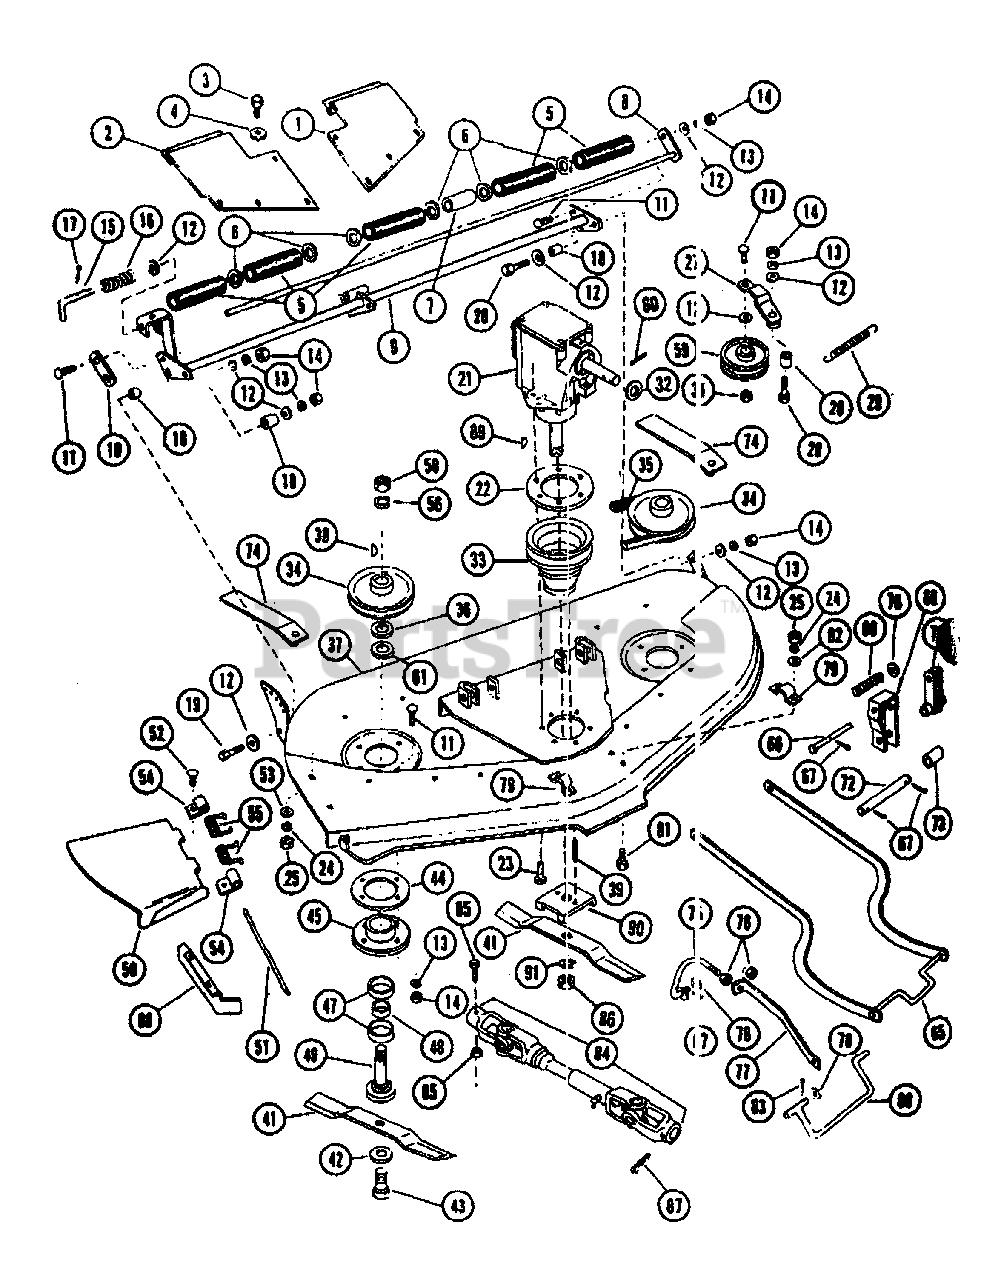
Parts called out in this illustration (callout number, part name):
1	SHIELD ASSEMBLY
2	R.H. BELT SHIELD
3	SCR-TAP .250-20X.50 HH F
4	WSHR-FL-STL.281X.62X.065 PL
6	WSHR-FL-STL.656X1.312X.095 PL
7	SPACER .692X.812X2.125
8	ROLLER SHAFT
9	ROLLER ADJUSTMENT
11	BLT-RDHDSQNK .38-16X1.0 PL
12	WSHR-FL-STL .438X1.0X.083 PL
13	WSHR-LK .375X.094 MED PL
14	NUT-HEX .375-16
16	SG-COMP .063X.63X1.75 WLD10
17	PIN-COTR .12X.75 PL
18	BSHG-SLV .377X.624X.235
19	BLT-HEX .38-16X1.25 PL GR 2
20	BLT-HEX .38-16X1.00 PL
21	MOWER GEAR CASE 42 IN
22	SHIM
23	BLT-LK .31-18X.75 GR 5
24	WSHR-LK .312X.097 PL HVY
25	NUT-HEX .312-18
26	BSHG-SLV .375X.625X.1.000
27	IDLER ARM
28	BLT-HEX .38-16X1.75 PL GR2
29	SG-TENS .125X.812X5.25 WLD 15
31	NUT-LK-JAM-CTR .375-16 PL
32	WSHR-FL-STL .754X1.000X.032
34	PLY-V 4.50 X .75 W/KEY SALEM
35	V-BELT, HA-WRAPPED
36	WSHR-FL-STL .781X1.250X.059 PL
37	DECK ASSEMBLY
38	KEY-WDRF .188X.75X.313 SAE 9
39	PIN-GRV .188X.75 TP A
40	SCR-MCH .31-18X1.00 SLFL PL
42	BELLEVILLE WASHER
43	BLT-HEX .44-20X1.00 GR5
45	FLANGED BEARING HOUSING
47	BRG-BALL .750X1.781X.61
48	SPACER .807X1.001X.445
49	SPINDLE SHAFT
50	CHUTE EXTENSION
51	CHUTE PIVOT ROD
52	BLT-RDHDSQNK .312-18X.62SHTPL
53	WSHR-FL-STL .38X.875X.083 PL
54	CHUTE HINGE
55	SG-TORS .080X.28X1.30
56	WSHR-LK-INT .750X.050 MED
58	NUT-JAM .75-16 PL
59	IDLER-FLAT 3.00 X .38 CLK.&CAP
60	PIN-ROLL .125X1.00
61	WSHR-FL-STL .755X1.375X.062 PL
65	MOWER HANGER
66	PIN-CLEV .498X4.50 YWZC
67	PIN-COTR .12X1.0 PL
68	SUPPORT CHANNEL
69	SG-COMP .62X.68X1.75
70	WSHR-FL-STL .531X1.062X.095 PL
72	PIN-CLEV .498X4.31 YWZC
73	SPACER .516X.749X.938
74	RAMP
75	ADJUSTING ROD
76	NUT .50-13 PL
78	WSHR-FL-STL.563X1.37X.109PL
80	SUPPORT SHAFT
81	BLT-RDHDSQNK .31-18X.75 GR5 PL
82	WSHR-FL-STL.344X.688X.065PL
83	PIN-COTR .25X1.50 ST PL
84	PTO SHAFT ASSEMBLY
85	SHEARBOLT & NUT ASSEMBLY
86	NUT-JAM .75-10 PL
87	PIN-HAIR INT .18X1.18X3.25 PL
88	ELEC START KIT-USA TEC #1133-1
89	KEY-WDRF .25X.750X.313 SAE91
90	BLADE TRAY
91	WSHR-LK .750X.188 MED PL
